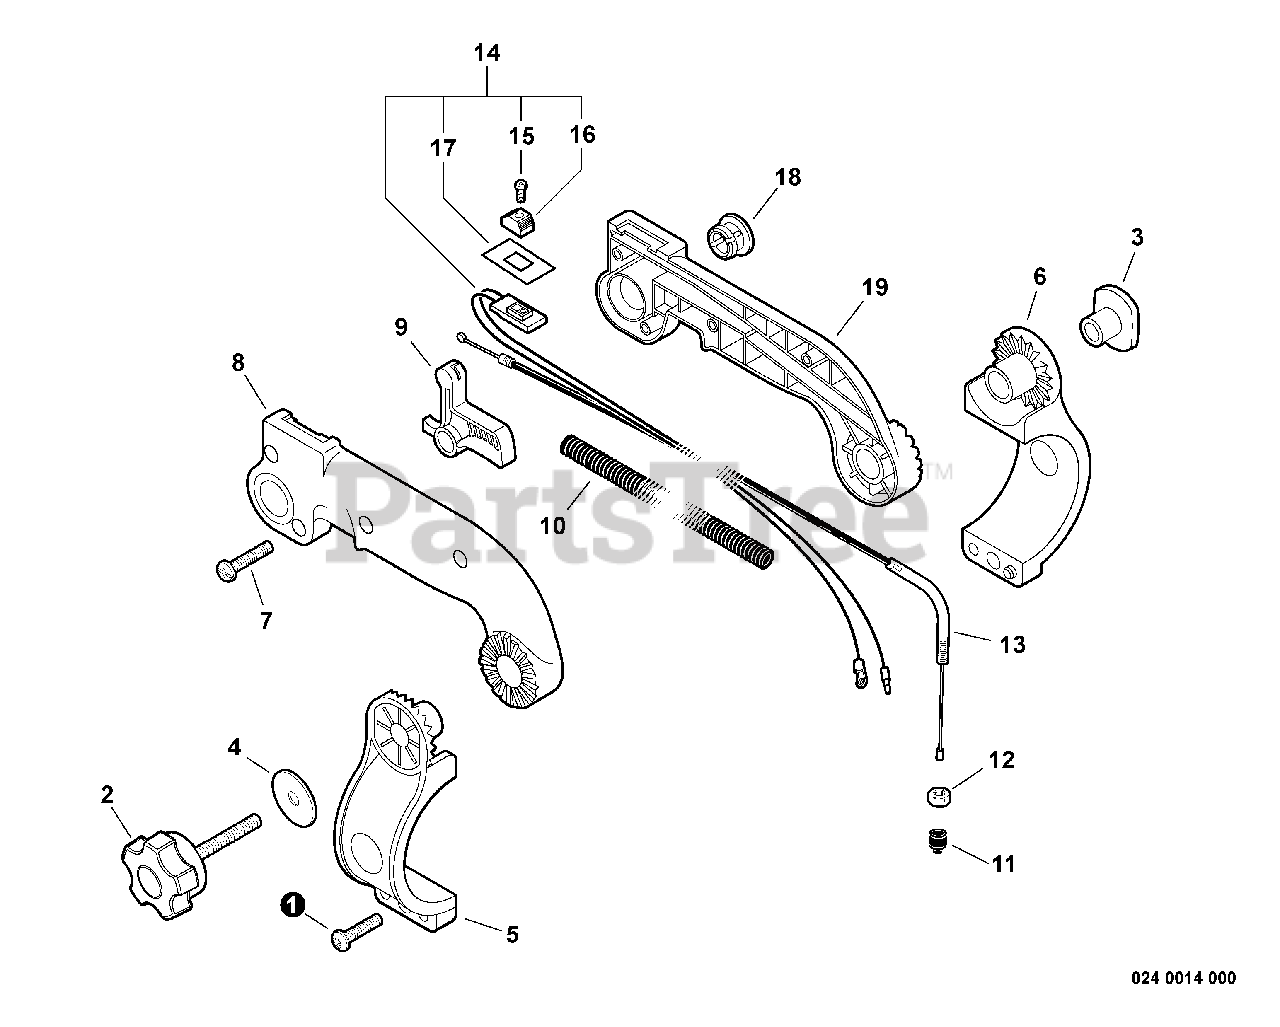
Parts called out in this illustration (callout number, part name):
1	SCREW - 5X20 -- TAPPING
2	THUMBSCREW
4	WASHER - 6
5	BRACKET, HANDLE - LEFT
6	BRACKET, HANDLE - RIGHT
7	SCREW - 4X22
8	HANDLE, FRONT - LEFT
9	TRIGGER, THROTTLE
10	TUBE, PROTECTIVE - CORRUGATED
11	CAP, DUST
12	LOCKNUT - 6
13	CABLE, THROTTLE
14	IGNITION SWITCH ASSY
15	SCREW - 3X10
16	KNOB, SWITCH - ORANGE
17	COVER, SWITCH - STOP
19	HANDLE, CONTROL - RIGHT
